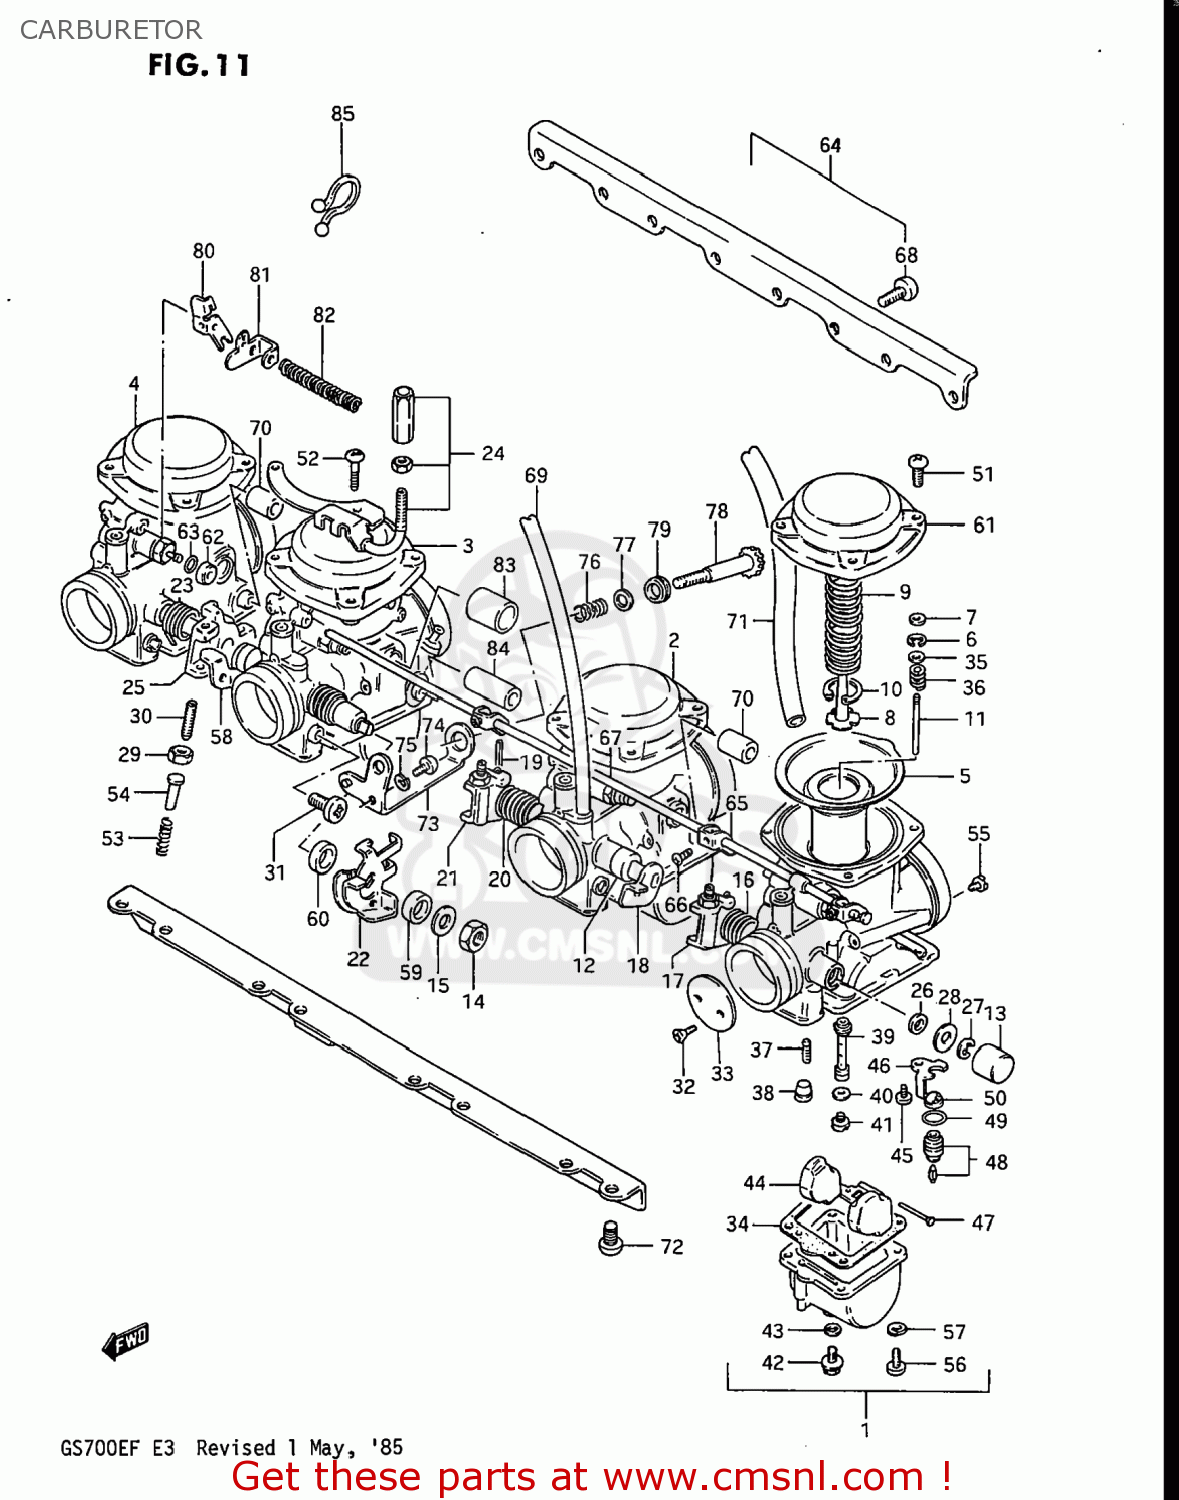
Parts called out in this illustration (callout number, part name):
1	CARBURETOR ASSEMBLY
2	CARBURETOR ASSEMBLY,MIDDLE,LEFT (ASB
3	CARBURETOR ASSEMBLY
4	CARBURETOR ASSEMBLY
5	DIAPHRAGM ASSEMBLY
6	CLIP,NEEDLE
7	RING
8	HOLDER,GUIDE
9	SPRING,DIAPHRAGM
10	E RING
11	NEEDLE JET
12	GASKET
13	CAP
14	NUT 8MM
15	WASHER
16	SPRING,THROTTLE SHAFT
17	SHAFT,THROTTLE
18	SHAFT,THROTTLE
19	PIN,THROTTLE SHAFT
20	SPRING,THROTTLE SHAFT
21	LEVER,THROTTLE SHAFT
22	LEVER ASSEMBLY,THROTTLE
23	SPRING,THROTTLE SHAFT
24	BRACKET,THROTTLE CABLE
25	SHAFT,THROTTLE
26	SEAL
27	E RING
28	GASKET,THROTTLE SHAFT (NAS)
29	NUT
30	SCREW
31	SCREW
32	SCREW
33	VALVE,THROTTLE (BUTTERFLY)
34	GASKET,FLOAT CHAMBER (NAS)
35	WASHER
36	SPRING
37	JET,PILOT(37.5)
38	PLUG,NEEDLE JET
39	JET,NEEDLE
40	WASHER,NEEDLE NOZZLE
41	JET,MAIN(122.5)
42	PLUG,DRAIN
43	GASKET (NAS)
44	FLOAT
45	SCREW 4X6
46	PLATE,NEEDLE VALVE FITING
47	PIN,FLOAT
48	VALVE ASSEMBLY,NEEDLE
49	O-RING,NEEDLE VALVE
50	FILTER
51	SCREW
52	SCREW
53	SPRING,THROTTLE SCREW
54	PIN,THROTTLE LEVER
55	JET
56	SCREW
57	LOCK WASHER
58	SHAFT,THROTTLE
59	RING
60	RING
61	COVER
62	CAP,STARTER VALVE
63	O RING
64	FLANGE ASSEMBLY,CARBURETOR
65	LEVER
66	SCREW,THROTTLE ADJUST
67	SHAFT,STARTER
68	SCREW
69	HOSE 4.5X8X390
70	NIPPLE,CARBURETOR
71	HOSE
72	SCREW 6X12
73	BRACKET,THROTTLE ADJUST
74	SCREW
75	LOCK WASHER
76	SPRING
77	WASHER
78	ADJUSTER
79	BUSH
80	LEVER,CHOKE CABLE
81	PLATE,CHOKE CABLE
82	SPRING,CHOKE CABLE
83	HOSE
84	NIPPLE,CARBURETOR
85	CLIP(ID:16)
